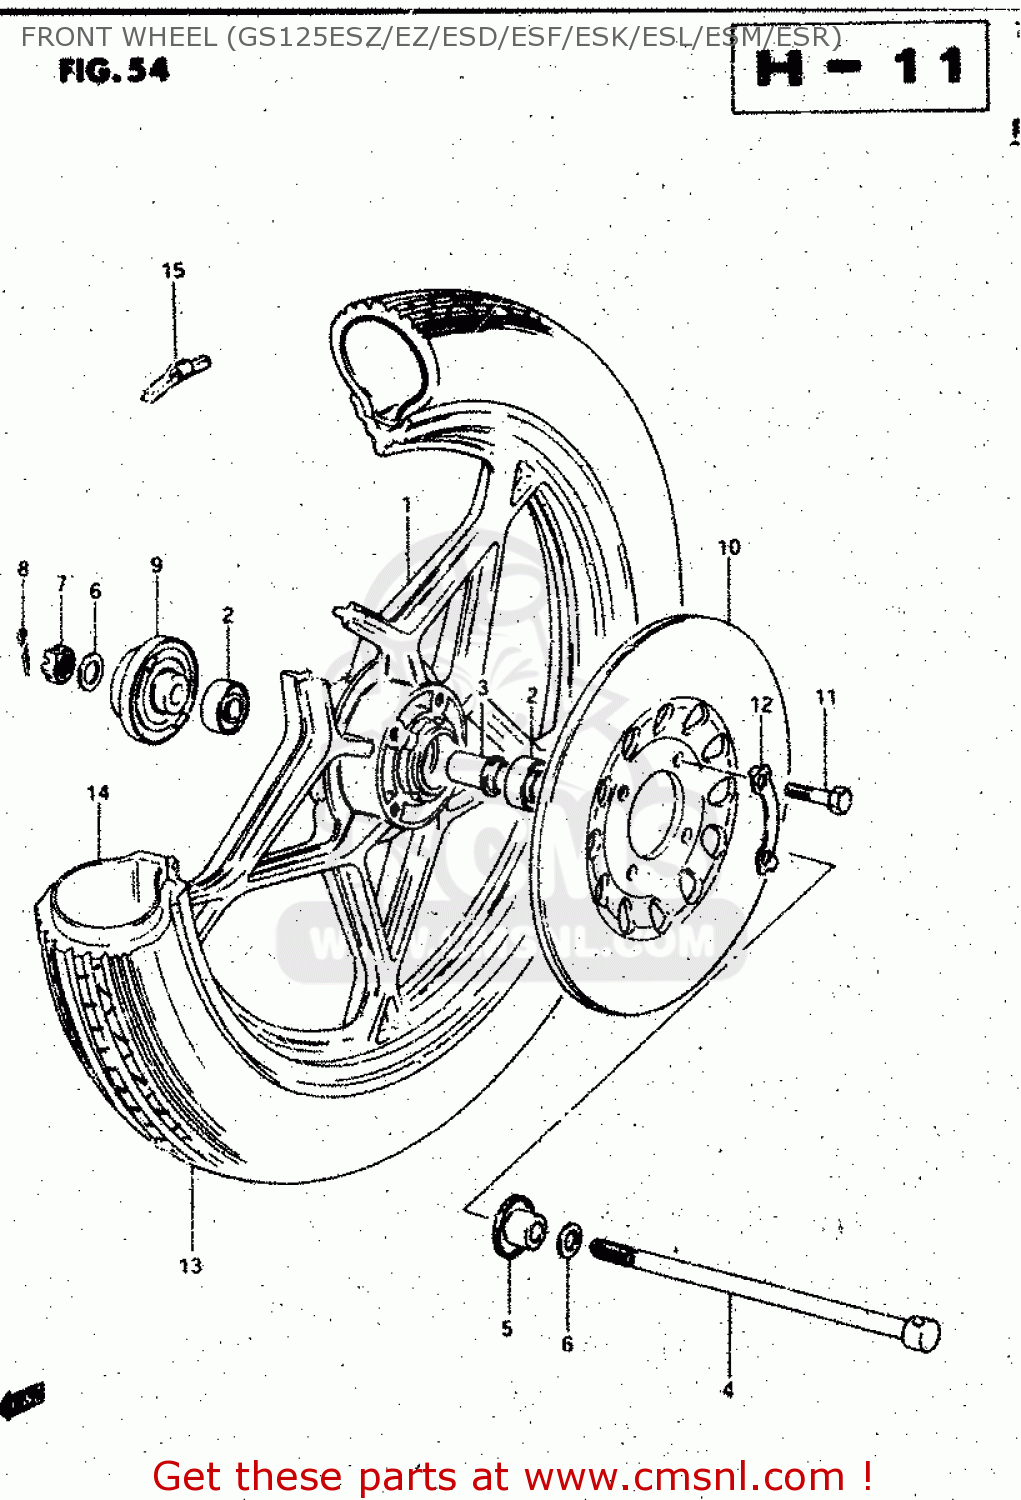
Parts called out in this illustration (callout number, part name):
1	WHEEL, FRONT (18X1.60) GOLD
2	BEARING
3	SPACER (12.6X19X52)
4	AXLE,FR
5	SPACER,FR AXLE,L
6	WASHER
7	NUT
8	COTTER PIN
9	BOX ASSY,SPEEDOMETER GEAR
10	DISC,FR BRAKE
11	BOLT(8X25)
12	WASHER
13	TIRE,FRONT
14	TUBE,INNER
15	BALANCER,WHEEL
